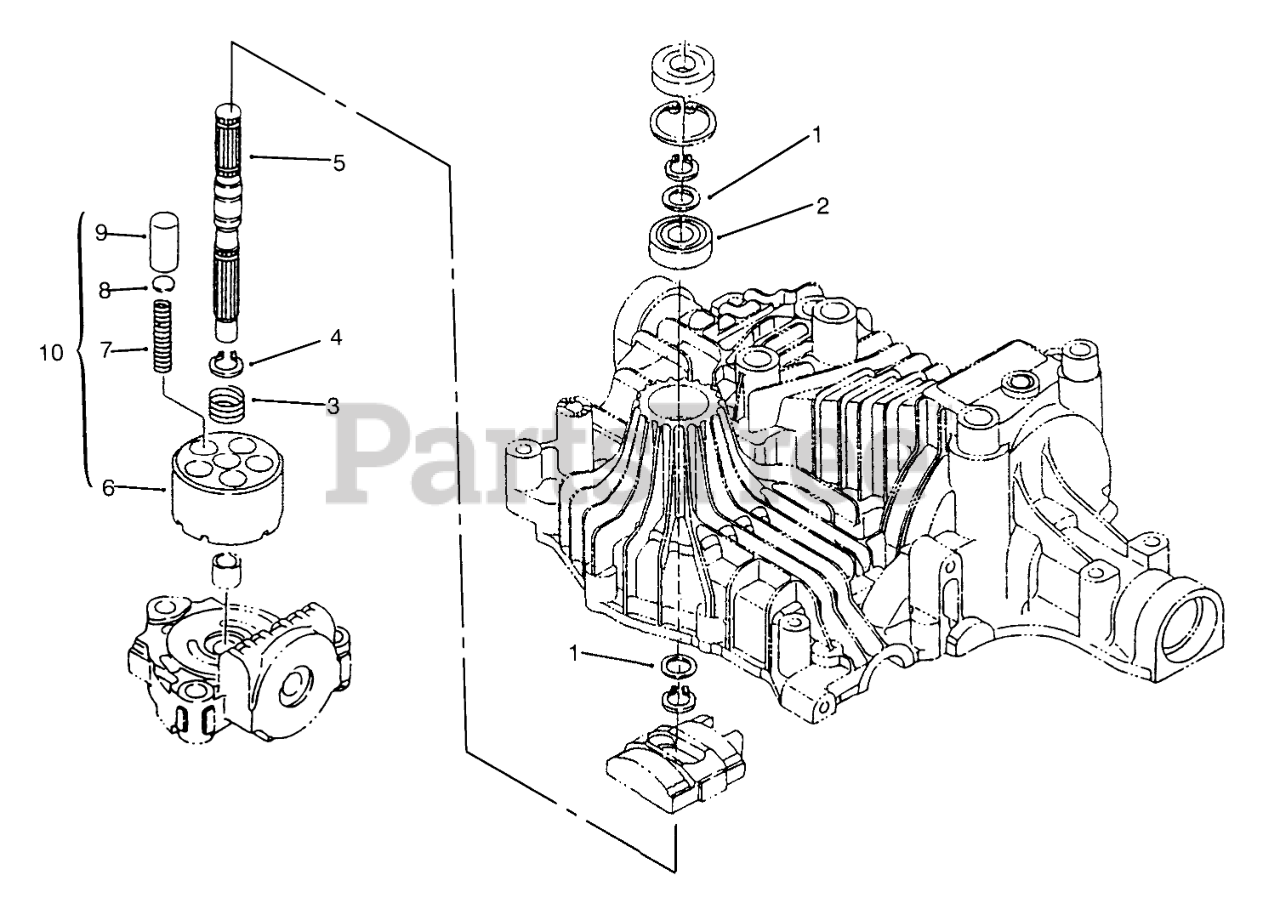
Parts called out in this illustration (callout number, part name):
1	Washer (Only On: 72043,72063,72103)
2	Bearing-Ball (Only On: 72043,72063,72103)
3	Spring (Only On: 72043,72063,72103)
4	Ring-Snap (Only On: 72043,72063,72103)
5	Shaft-Pump (Only On: 72043,72063,72103)
10	Cylinder ASM INCL 6-9 (Only On: 72043,72063,72103)
